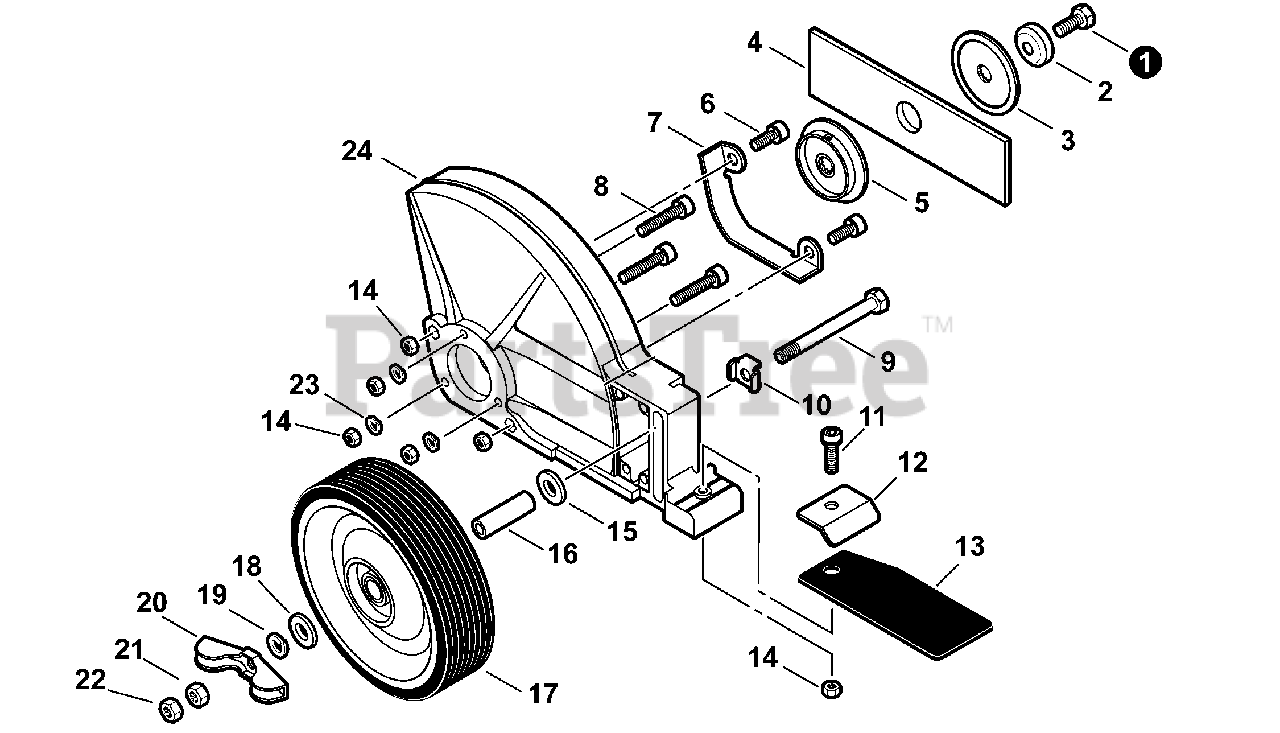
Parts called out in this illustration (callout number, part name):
2	GUARD, BOLT
3	PLATE, ADAPTOR - LOWER
4	BLADE - 2 PK
5	PLATE, ADAPTOR - UPPER
6	BOLT M5×12
7	PROTECTOR, GEAR CASE
8	BOLT M5×25
9	BOLT M8×90
10	PLATE, LOCK
11	BOLT M5×16
12	PLATE, FLAP
13	FLAP, DEBRIS
14	NUT M5
17	WHEEL
19	WASHER, SPRING 8
20	KNOB, FASTENER
22	NUT, LOCK M8
23	WASHER, SPRING 5
24	SHIELD, BLADE
